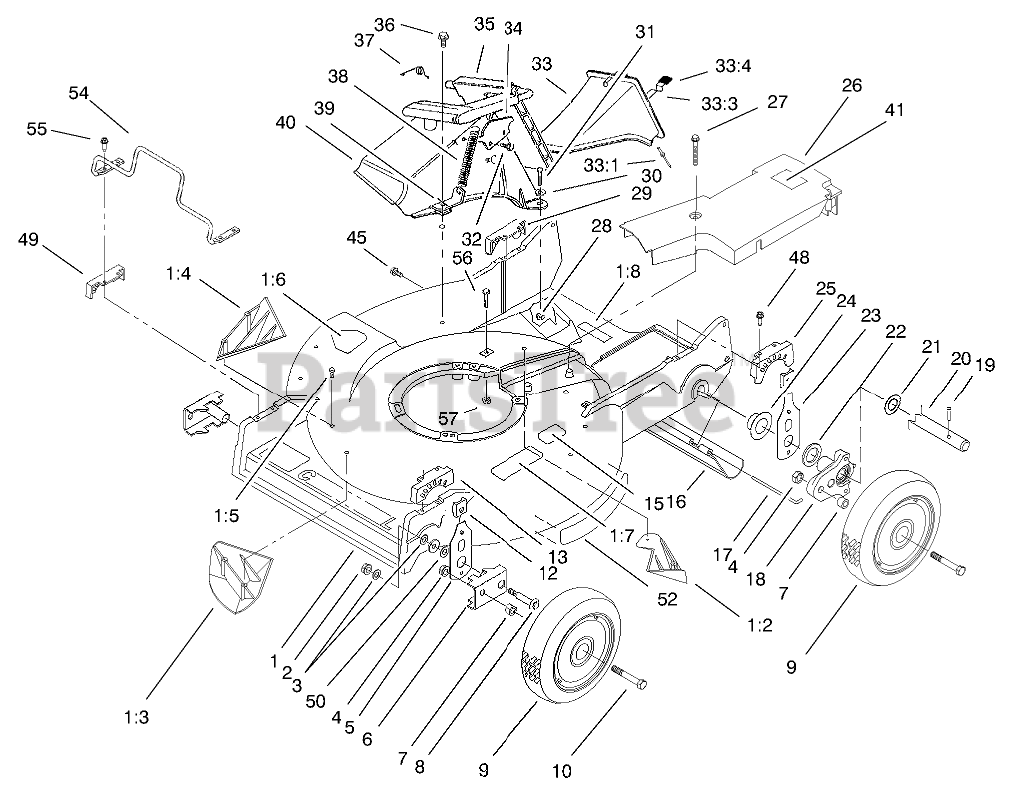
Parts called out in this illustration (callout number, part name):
1	HOUSING ASM
1:2	KICKER-REAR
1:3	KICKER-FRONT
1:4	KICKER-RH
1:5	SCREW-PPH
1:6	DECAL-DANGER
1:7	DECAL-WARNING
1:8	DECAL-WARNING
2	NUT-LOCK
3	WASHER
4	NUT-LOCK, CONE
5	FRONT SPRING ARM ASM
6	ARM-PIVOT, FRONT
7	SPACER-WHEEL
8	BOLT-WHEEL
9	WHEEL AND TIRE ASM
10	SCREW-HH
12	KNOB-ARM
13	QUADRANT-FRONT, LH
15	Decal-Safety
16	SHIELD-TRAILING
17	ROD-SHIELD
18	PIVOT ARM ASM
19	PIN-SPIROL
20	SHAFT-AXLE, REAR
21	WASHER-PLAIN
22	WASHER
23	REAR SPRING ARM ASM
24	CAP-END
25	QUADRANT-REAR, LH
26	COVER-BELT
27	SCREW-HHFTF
28	NUT-LOCK, NI
29	QUADRANT-REAR, RH
30	WASHER-FLAT
31	SCREW-HH
32	SCREW-PLASTITE
33	DISCHARGE PLUG ASM
33:1	RIVET-HEAD, FLAT
33:3	LATCH-PLUG, DISCHARGE
33:4	GRIP-LATCH
34	LATCH-PLATE
35	DISCHARGE DOOR ASM
36	SCREW-HWH
37	RETAINER-DOOR
38	SPRING-DOOR
39	BRACKET-SPRING
40	TUNNEL-DISCHARGE
41	LABEL-GREASE, HP
45	SCREW AND WASHER ASM
48	SCREW-HWHTF
49	QUADRANT-FRONT, RH
50	WASHER-THRUST
52	DECAL-RECYCLER
54	GUARD-ENGINE
55	SCREW-HWHTF
56	SCREW-HH
57	NUT-LOCK, NI
